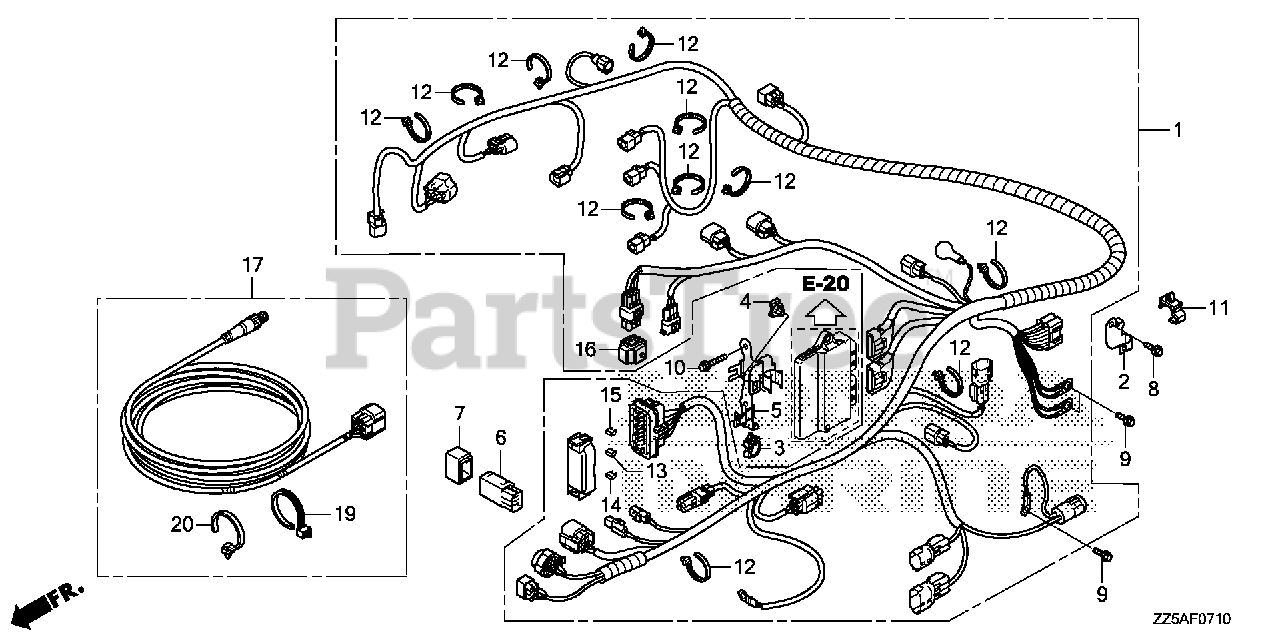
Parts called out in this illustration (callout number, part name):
1	WIRE HARNESS ASSY., MAIN
2	BRACKET C, CONNECTOR
3	CLAMP, WIRE
4	CLIP, CONNECTOR HOLDER (B)
5	BRACKET, FUSE BOX
6	RELAY ASSY., MAIN
7	SUSPENSION, RELAY
8	BOLT, FLANGE (6X14) (CT200)
9	BOLT, FLANGE (6X12)
10	BOLT, FLANGE (6X28) (CT200)
11	CLIP, WIRE HARNESS (13MM) (GRAY)
12	CLIP, HARNESS BAND (145MM) (BLACK)
13	FUSE, MINI (10A)
14	FUSE, MINI (15A)
15	FUSE, MINI (30A)
16	SUSPENSION, CONNECTOR
17	KIT, CABLE (6FT) (NMEA)
19	TIE, CABLE
20	CLIP, HARNESS BAND (155.3MM) (BLACK)
